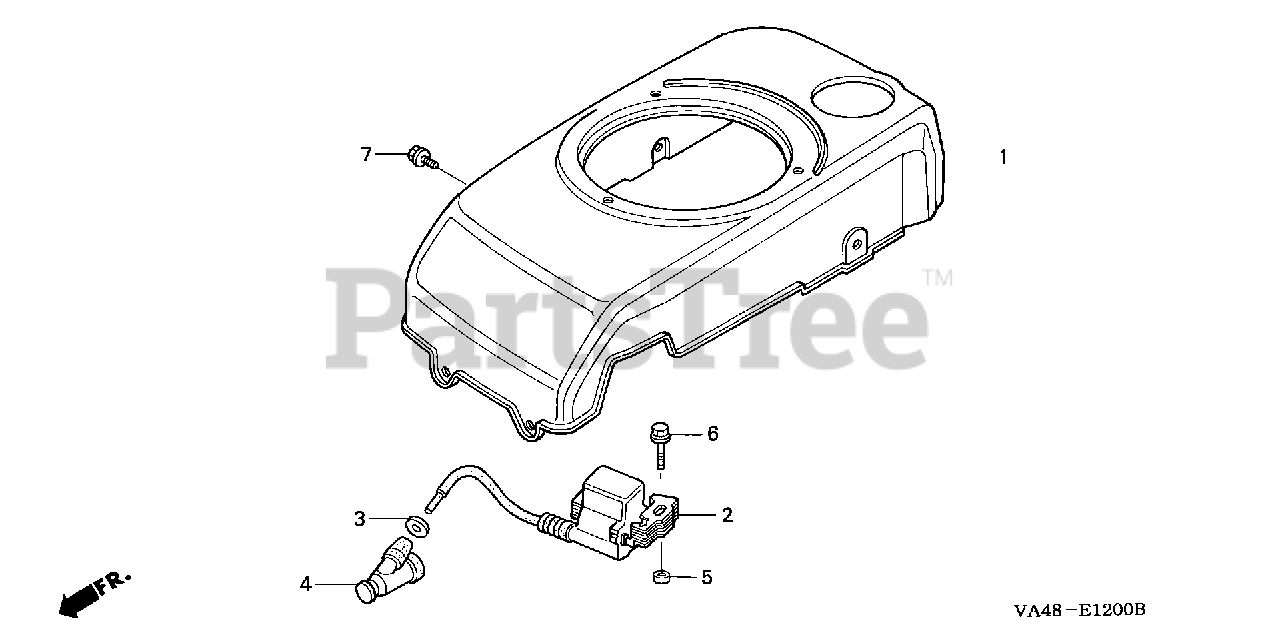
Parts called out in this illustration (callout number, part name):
1	COVER, FAN *R8* (BRIGHT RED)
2	COIL ASSY., IGNITION
3	GROMMET, IGNITION WIRE
4	TERMINAL ASSY., IGNITION
6	BOLT, FLANGE (6X25) Use up to Engine SN 2056819.
7	BOLT, FLANGE (6X10)
